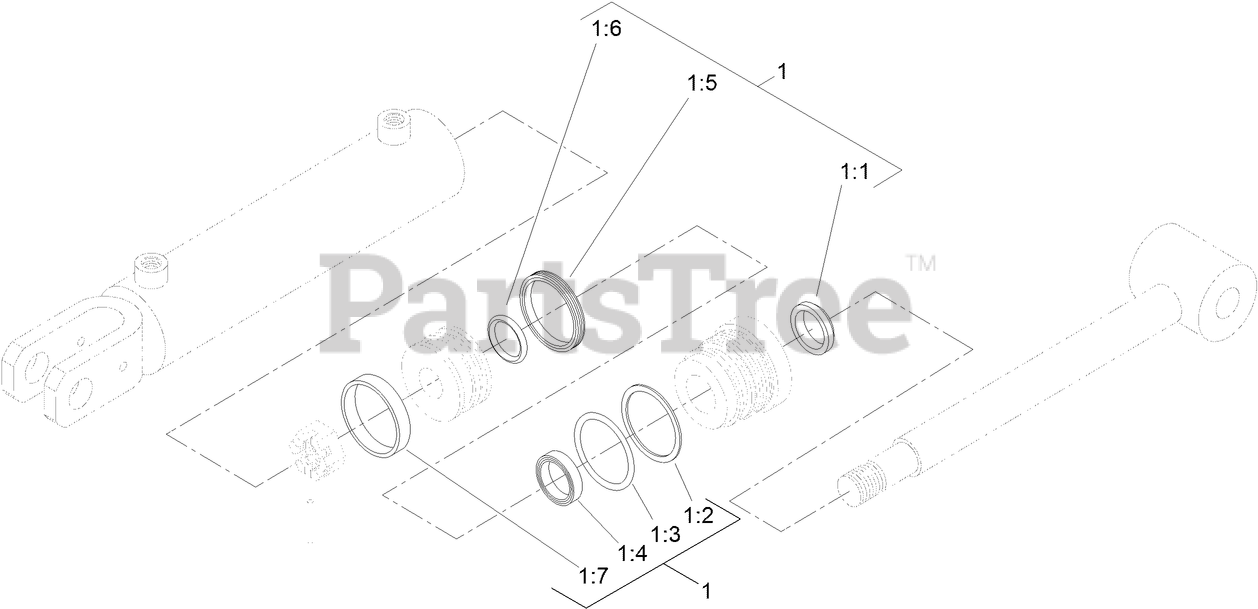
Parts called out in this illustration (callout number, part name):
1	KIT-SEAL
1:1	SEAL-Shaft
1:2	Ring-Back Up
1:3	O-RING
1:4	SEAL
1:5	SEAL
1:6	O-RING
1:7	WIPER
